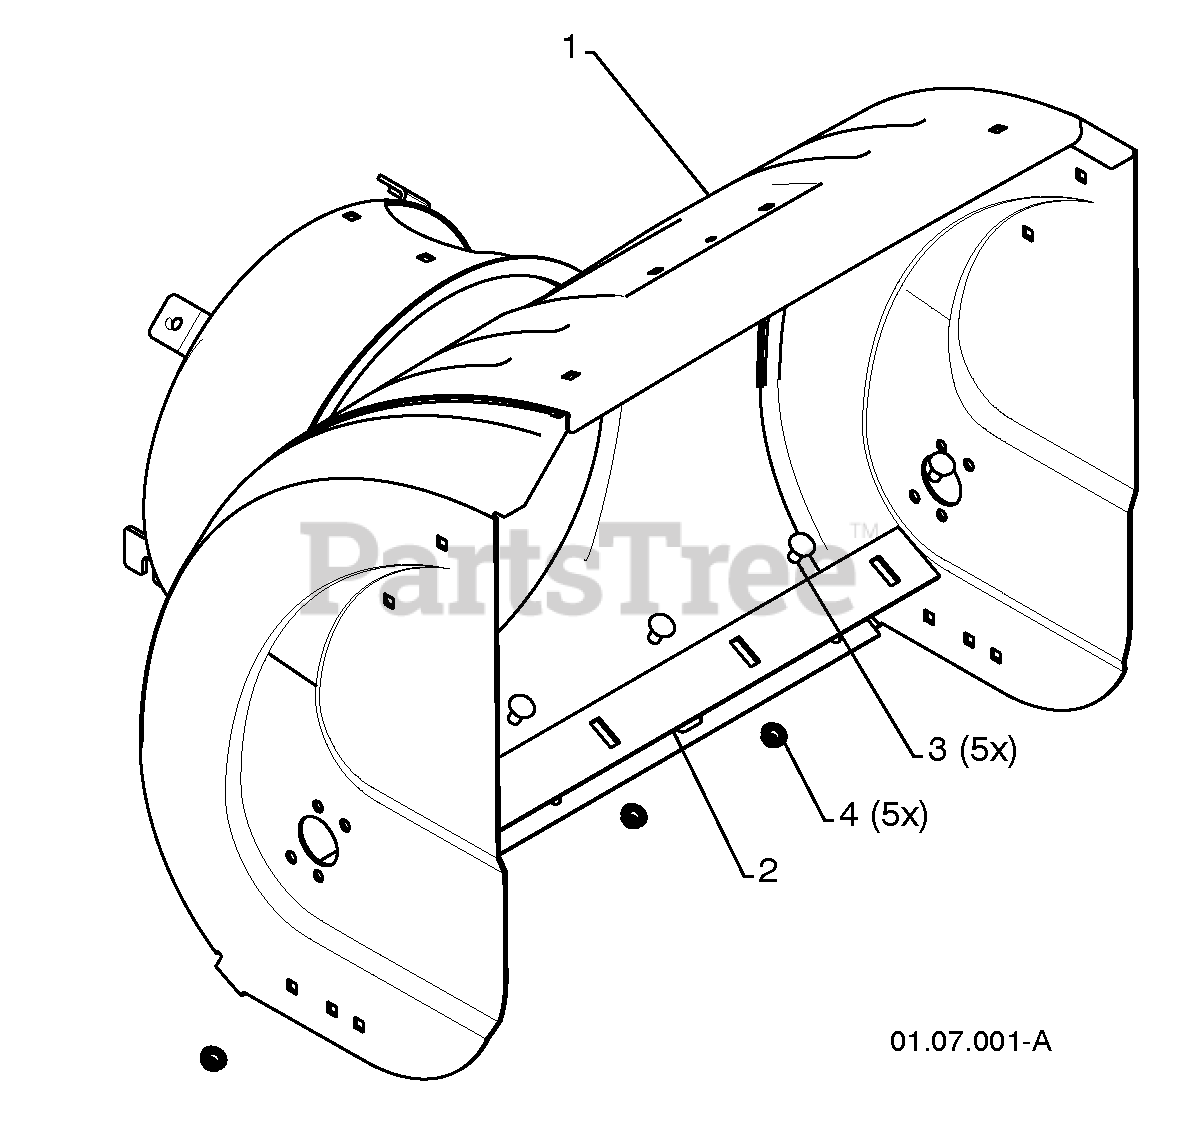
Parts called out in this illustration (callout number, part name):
1	AUGER HOUSING
2	SCRAPPER BAR
3	CARRIAGE BOLT 5/16-18 X .625
4	NUT 5/16-18
